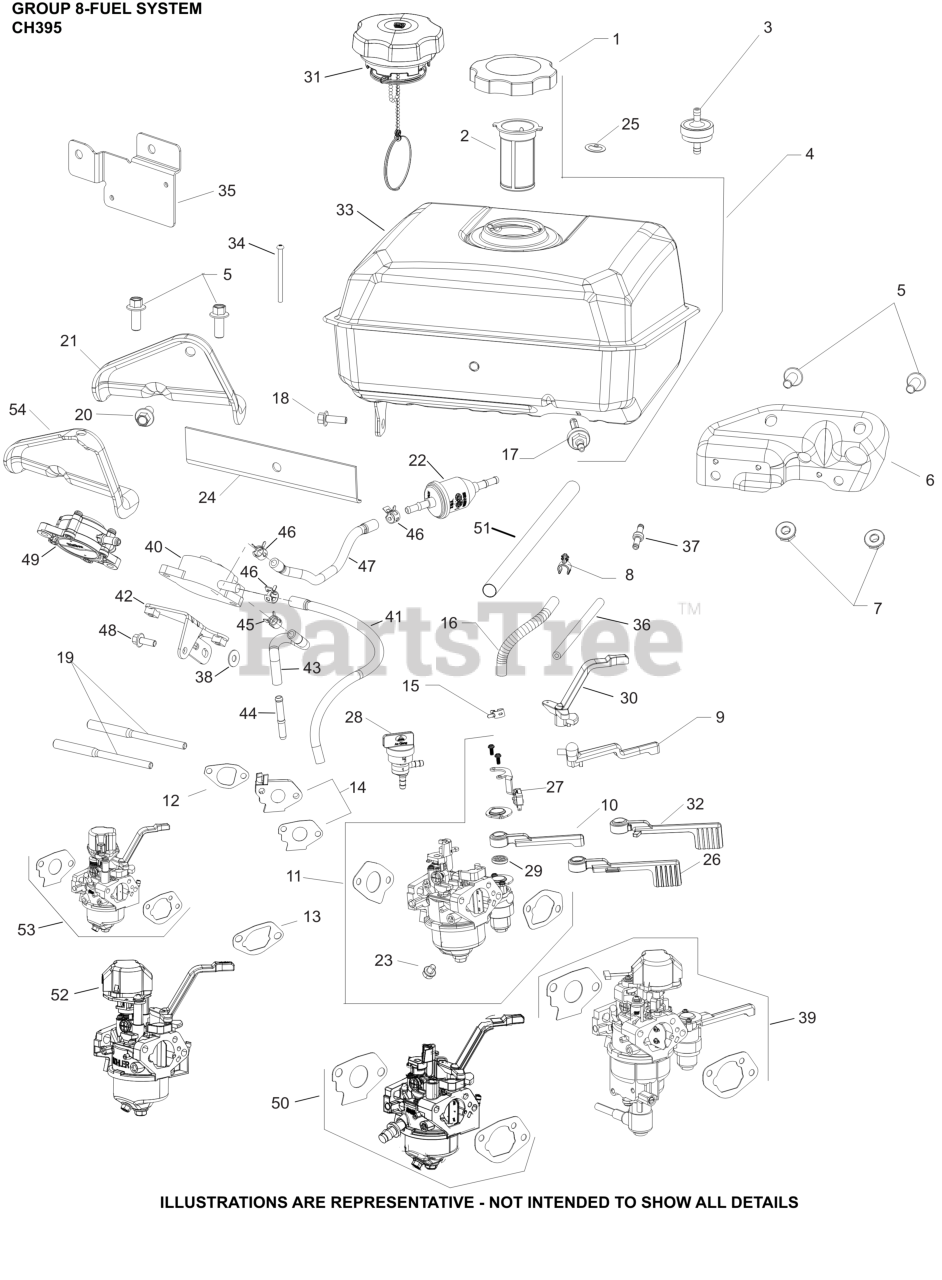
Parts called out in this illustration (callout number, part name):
1	CAP, FUEL TANK
2	FILTER, FUEL TANK
5	SCREW, M8 X 20
6	BRACKET, FUEL SUPPORT ASSEMBLY
7	NUT, FLG M8X1.25
8	CLIP, FUEL HOSE
9	LEVER, CHOKE
10	LEVER, FUEL SHUTOFF
11	KIT, CARBURETOR
14	INSULATOR AND GASKET KIT
15	CLAMP, FUEL LINE
16	LINE, FUEL (10"-CUT TO LENGTH)
17	FITTING, FUEL ASSY
19	STUD, CARBURETOR
20	SCREW, FLG 8X1.25X16
21	BRACKET, FUEL SUPPORT
23	SCREW, BOWL DRAIN
25	KIT, FUEL SCREEN
29	SEAL, INLET VALVE
33	TANK, FUEL
NI	TOOL, SPARK PLUG WRENCH ASSY
NI	KIT, HIGH ALT (4000-8000 FT)
NI	KIT, HIGH ALT (8,000+ FT)
NI	KIT, CARBURETOR REPAIR
